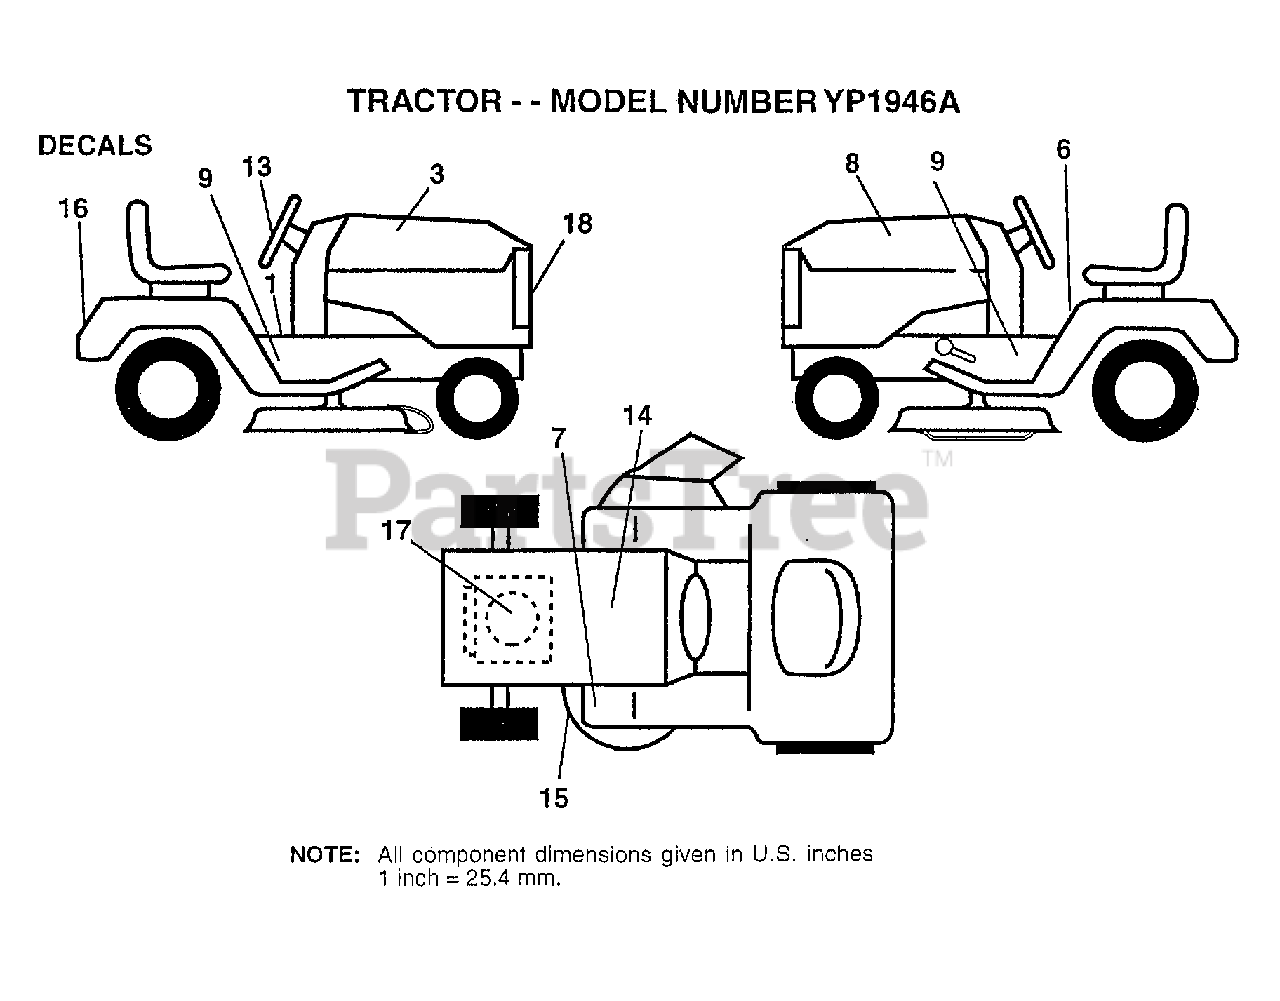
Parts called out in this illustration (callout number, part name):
1	"DECAL DASH,OPER."
3	"DECAL HOOD,RH 19H"
6	"DECAL DANGER,FEND"
9	"DECAL CHASSIS,46"""
13	DECAL INS STRG WH
14	DECAL.BATRY.3-3908
15	"DECAL.V.BELT.44"""
16	DECAL FENDER
17	DECAL, HP ENGINE
